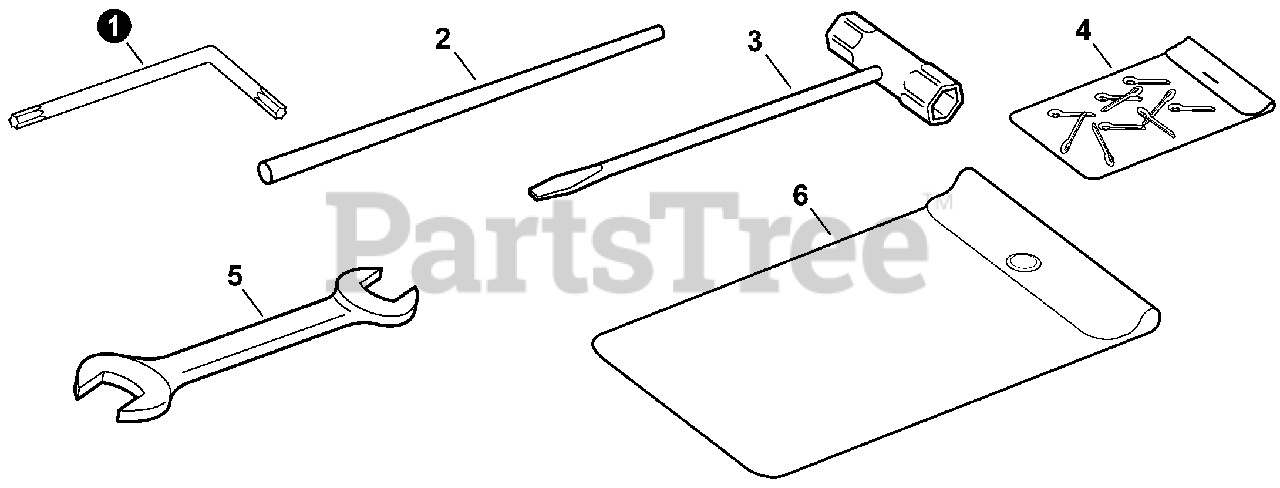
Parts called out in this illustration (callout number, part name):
1	WRENCH, T27 80×30
2	TOOL, LOCKING 5×120 MM
3	T-WRENCH 17x-19 L200
4	PIN, COTTER 2×22
5	SPANNER 8×10
6	BAG, TOOL
